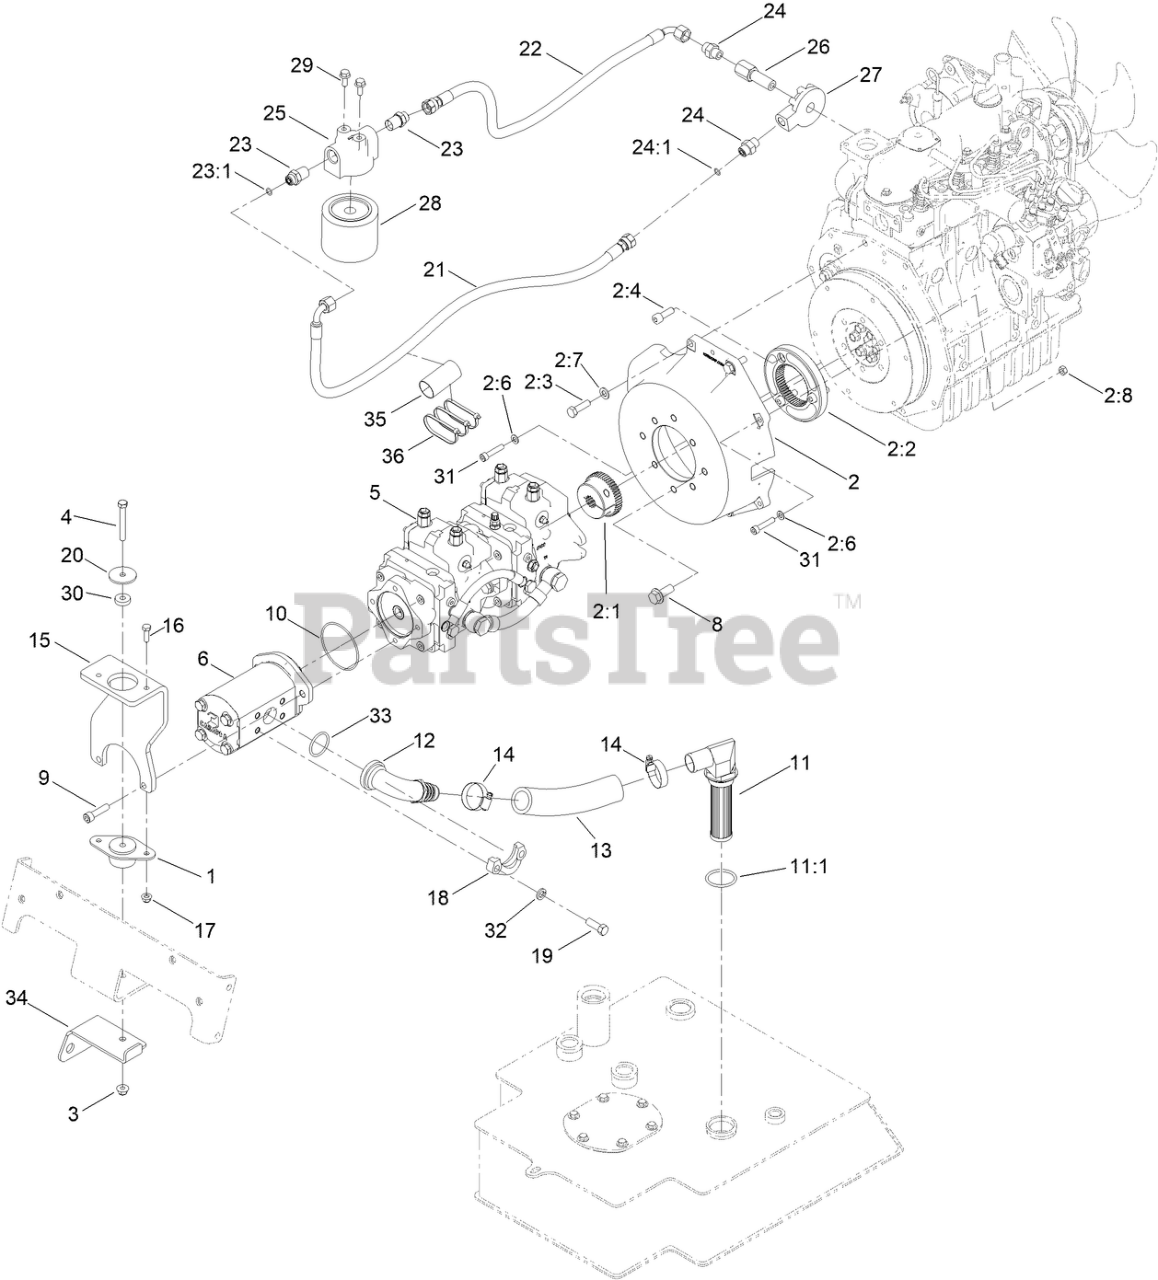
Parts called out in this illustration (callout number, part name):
1	MOUNT-ENGINE
2	MOUNT-PUMP
2:1	HUB-PUMP
2:2	FLANGE-COUPLER
2:3	SCREW-HH
2:4	SCREW-HSH
2:6	WASHER-PLAIN
2:7	WASHER-FLAT
2:8	NUT-HEX
3	NUT-HF, NI
4	SCREW-HH
5	PUMP-TANDEM
6	PUMP-GEAR
8	SCREW-HHF
9	SCREW-SH
10	O-RING
11	STRAINER FITTING ASM
11:1	O-RING
12	FITTING
13	HOSE-SUCTION
15	BRACKET-SUPPORT, PUMP
16	SCREW-HH
17	NUT-HF, NI
18	FLANGE
19	SCREW-HH
20	WASHER-REBOUND
21	HYD HOSE ASM
22	HYD HOSE ASM
23	FITTING-HYD
23:1	O-RING
24	FITTING-HYD
24:1	O-RING
25	BASE-FILTER
26	PIPE-JOINT
27	BASE-FILTER
28	FILTER-OIL
29	SCREW-HHF
30	SPACER
31	SCREW-HSH
32	WASHER-LOCK
33	O-RING
34	BRACKET-BULKHEAD
35	PROTECTOR-HOSE
36	TIE-CABLE
